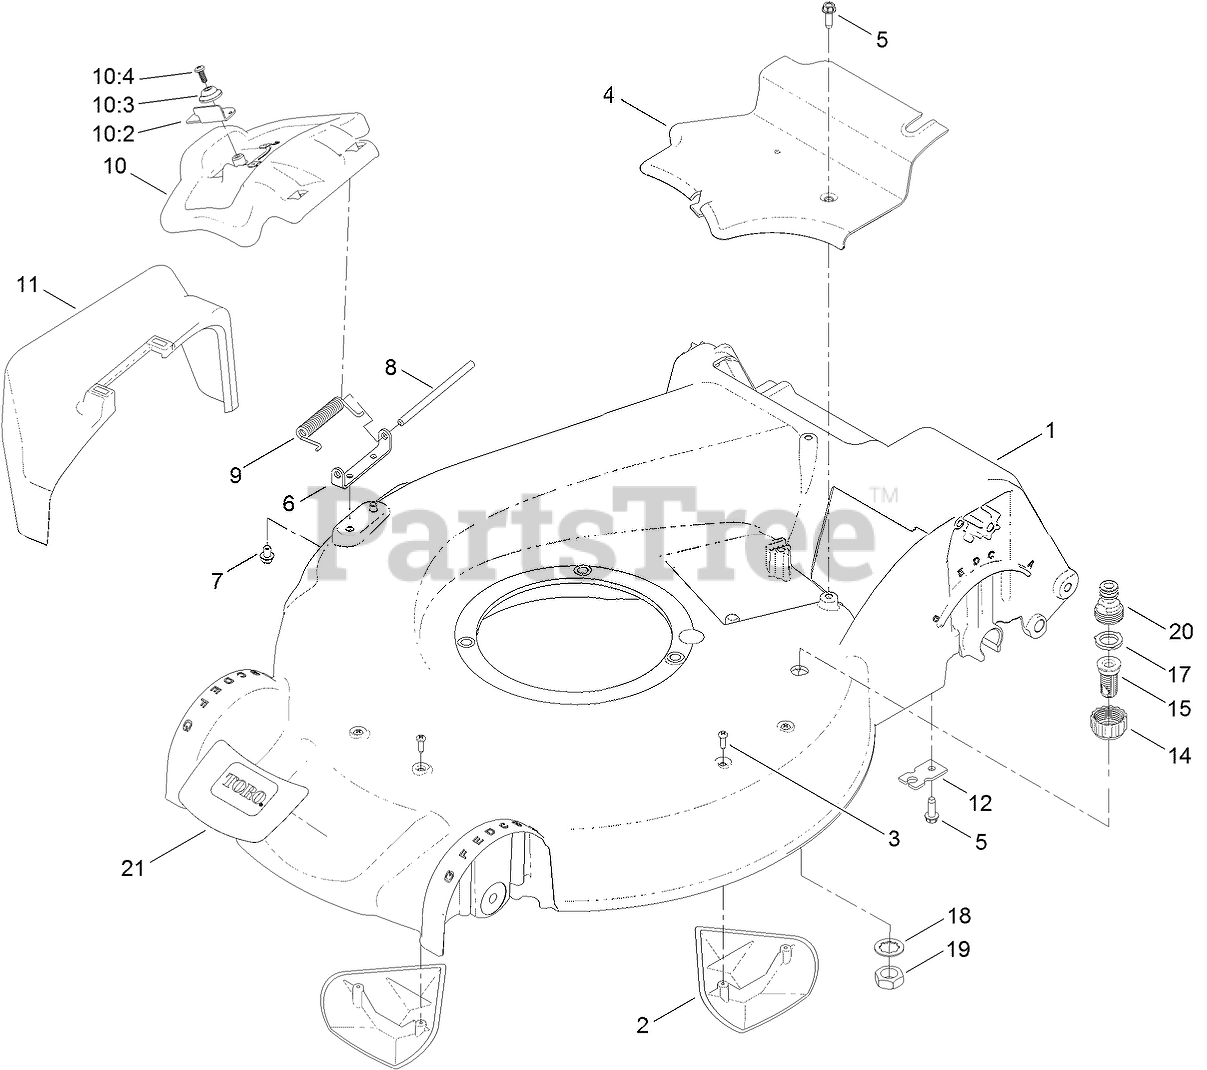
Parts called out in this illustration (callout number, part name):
1	HOUSING ASM
2	KICKER-HOUSING
3	SCREW-PPH
4	COVER-BELT
5	SCREW-HWHTF
6	BRACKET-COVER
7	SCREW-HWH
8	ROD-COVER
9	SPRING-TORSION
10	DISCHARGE DOOR ASM
10:2	LATCH-DOOR
10:3	CAP-DOOR
10:4	SCREW-PLASTITE
11	CHUTE-DISCHARGE, SIDE
12	BRACKET-CABLE, TRACTION
14	COUPLING-HOSE, WASHOUT PORT
15	PORT-WASHOUT
17	WASHER-SEAL, WASHOUT PORT
18	WASHER-TOOTH, INTERNAL
19	NUT-JAM
20	ADAPTER-CONNECT, QUICK
21	DECAL-DECK
